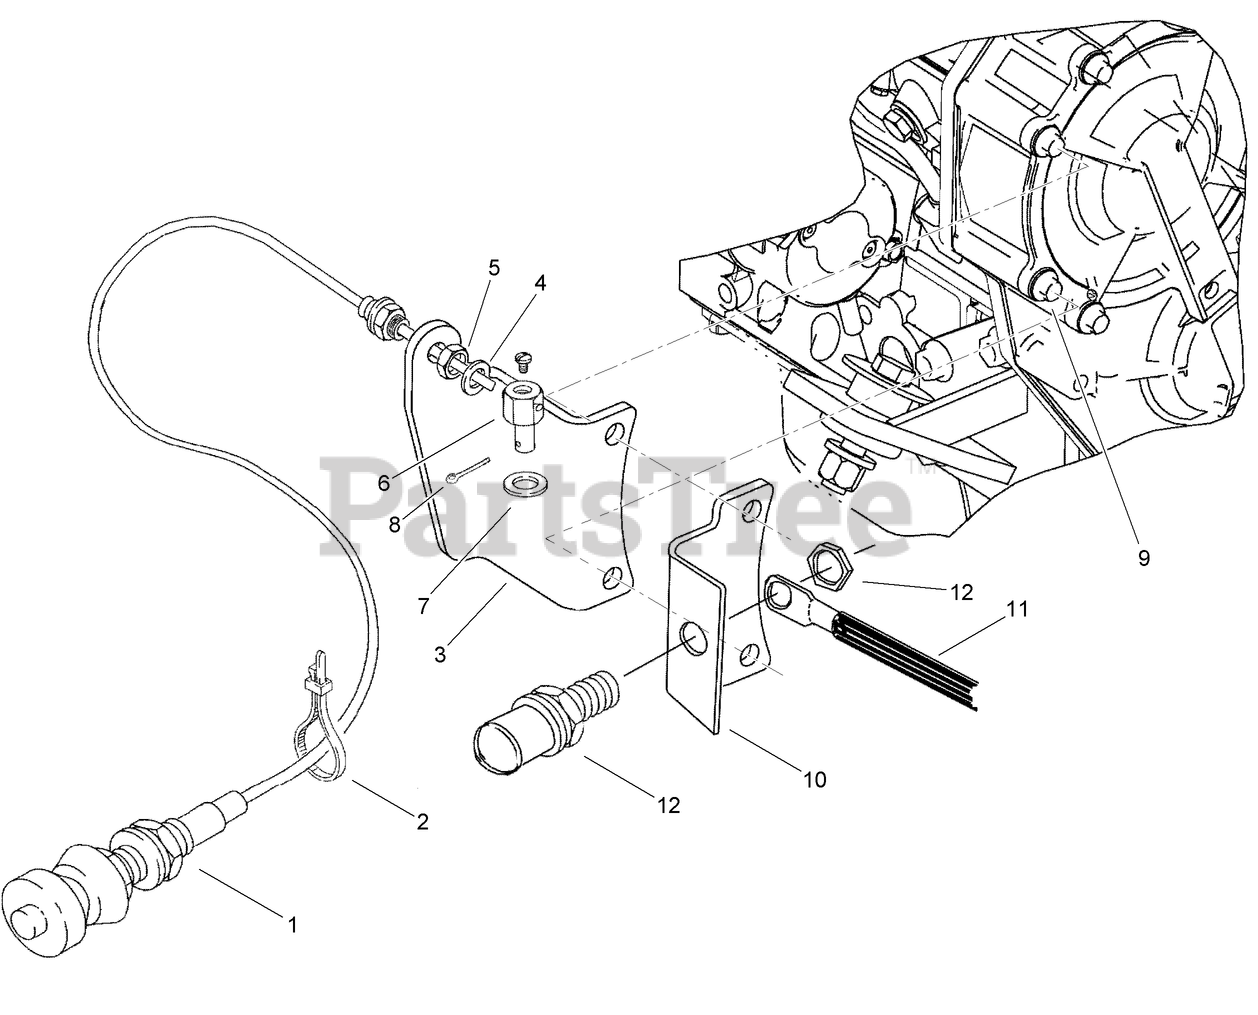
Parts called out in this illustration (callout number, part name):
1	CABLE-THROTTLE
2	STRAP - Tie, 15 inch, Nylon, Retaining
3	BRACKET - Mounting, Cable
4	WASHER-FLAT
5	NUT-JAM, HEX
7	WASHER-FLAT
8	PIN - Cotter .094 x 1.00 in Zn
9	SCREW, METRIC FLANGE w/BODY - M8 x 80 (used with optional remote battery post)
9	KIT - Remote Battery Post
9	SCREW, METRIC FLANGE w/BODY - M8 x 90 (used with optional remote battery post kit AU111049)
10	PLATE - Remote Battery Post Mounting (used with optional remote battery post kit AU111049)
11	CABLE - Starter
12	POST - Remote Battery (used with optional remote battery post kit AU111049)
